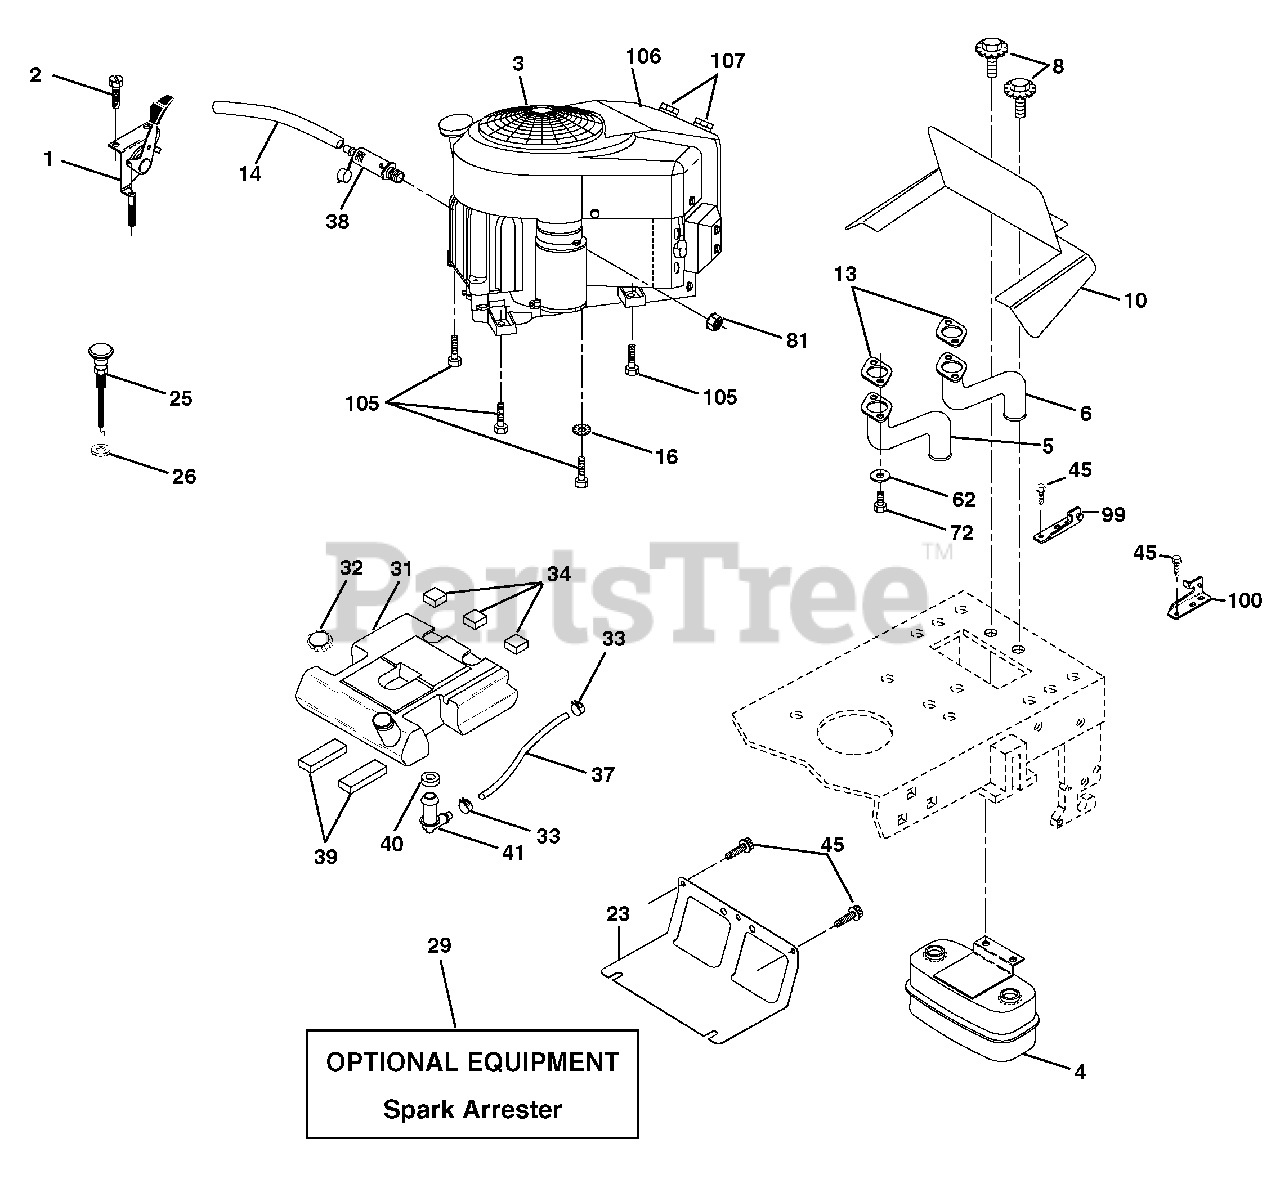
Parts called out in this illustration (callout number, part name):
1	Control, Throttle
2	Screw, Hex Head, Thread Cutting 1/4-20 x 5/8
4	Muffler
5	Tube, Exhaust, LH
6	Tube, Exhaust, RH
7	Clip Insulated
8	Bolt 5/16-18 UNC x 3/4 w/Sems
10	Shield, Browning
13	Muffler Gasket
14	Tube Drain Oil Easy
16	Washer, Lock, External Tooth 3/8
23	Shield, Browning / Debris Guard
25	Choke Control
26	Nut, Keps 3/8-24 UNF
29	Kit, Spark Arrestor
31	Tank Fuel 3 50 Rear
32	Cap Fuel Gauge
33	Clamp, Hose
34	Pad, Spacer
37	Line, Fuel
38	Plug Drain Oil Easy
39	Pad, Idler
40	Bushing
41	Stem, Fuel Tank
45	Screw Hex wsh Thdrol 3/8-16 x 3/4
62	Washer Lock 5/16
72	Screw Hex Hd Cap 5/16-18 x 3/4
81	Nut Keps Hex 1/4-20 Unc
99	Bracket Asm Pivot Lh Raised
100	Bracket Asm Pivot Rh Raised
105	Screw 3/8-16 x 1
106	Control Cover
